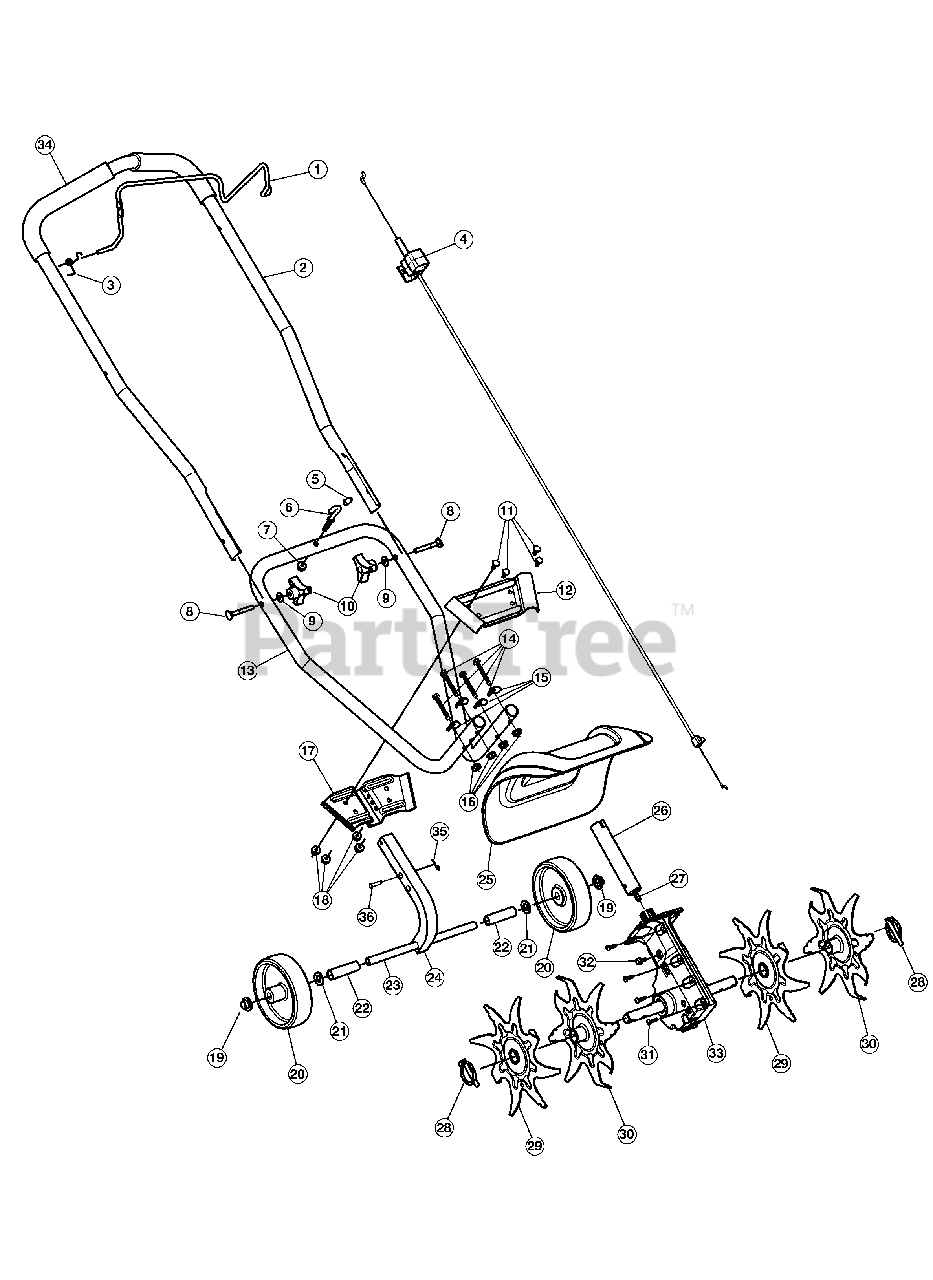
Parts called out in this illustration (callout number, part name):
4	Throttle Cable
6	Eyelet Bolt
9	Washer
12	Bracket, Upper
14	Bolt
15	Washer
17	Bracket, Lower
20	Wheel (Incl. 19)
24	Tube, Square
26	Tube (Incl. 27)
27	Flex Shaft
29	Tine (Left Inner, Right Outer)
30	Tine (Left Outer, Right Inner)
33	Gearbox (Incl. 31)
34	Foam Grip
35	Cotter Pin
36	Clevis Pin
